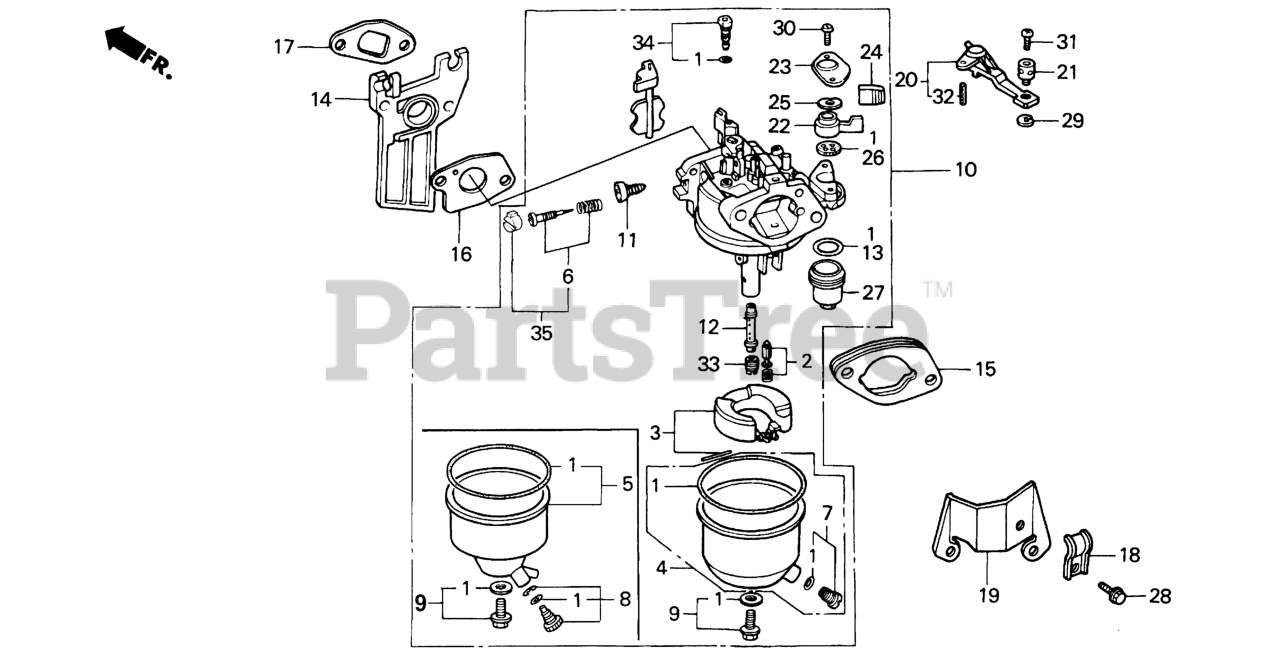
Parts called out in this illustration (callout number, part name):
1	GASKET SET
2	VALVE SET, FLOAT (CARBURETOR NO.) (SEAT NOT INCLUDED)
3	FLOAT SET
4	CHAMBER SET, FLOAT (CARBURETOR NO.)
4	CHAMBER SET, FLOAT (CARBURETOR NO.) (FOR BE12A A)
6	SCREW SET, PILOT (Honda Code 1441500). (CARBURETOR NO.)
7	SCREW SET, DRAIN (Honda Code 1672187). (CARBURETOR NO.)
9	SCREW SET B
9	SCREW SET
10	CARBURETOR ASSY. (BE07A D)
10	CARBURETOR ASSY. (BE07A E)
11	SCREW, THROTTLE STOP
12	NOZZLE, MAIN
13	GASKET, FUEL STRAINER CUP
14	INSULATOR, CARBURETOR
15	SPACER, CARBURETOR
16	GASKET, CARBURETOR
17	GASKET, INSULATOR
18	HOLDER, CONTROL CABLE Use from Engine SN 2327377.
19	STAY, CHOKE CONTROL
20	LEVER, CHOKE (REMOTE)
21	HOLDER, CABLE
22	LEVER, VALVE
23	PLATE, LEVER SETTING (CARBURETOR NO.)
25	SPRING, PETCOCK LEVER (CARBURETOR NO.)
26	GASKET, VALVE
27	CUP, FUEL STRAINER
28	BOLT, FLANGE (5X10) Use from Engine SN 2327377.
29	CIRCLIP (5MM) Use from Engine SN 2327377.
30	SCREW, PAN (3X6)
30	SCREW, PAN (3X8)
31	SCREW, PAN (4X6)
32	PIN, SPRING (2X12)
33	JET, MAIN (#65) Use up to Engine SN BB30A D.
33	JET, MAIN (#68) Use up to Engine SN BB30A D.
33	JET, MAIN (#70) Use up to Engine SN BB30A D.
34	JET SET, PILOT (#35)
